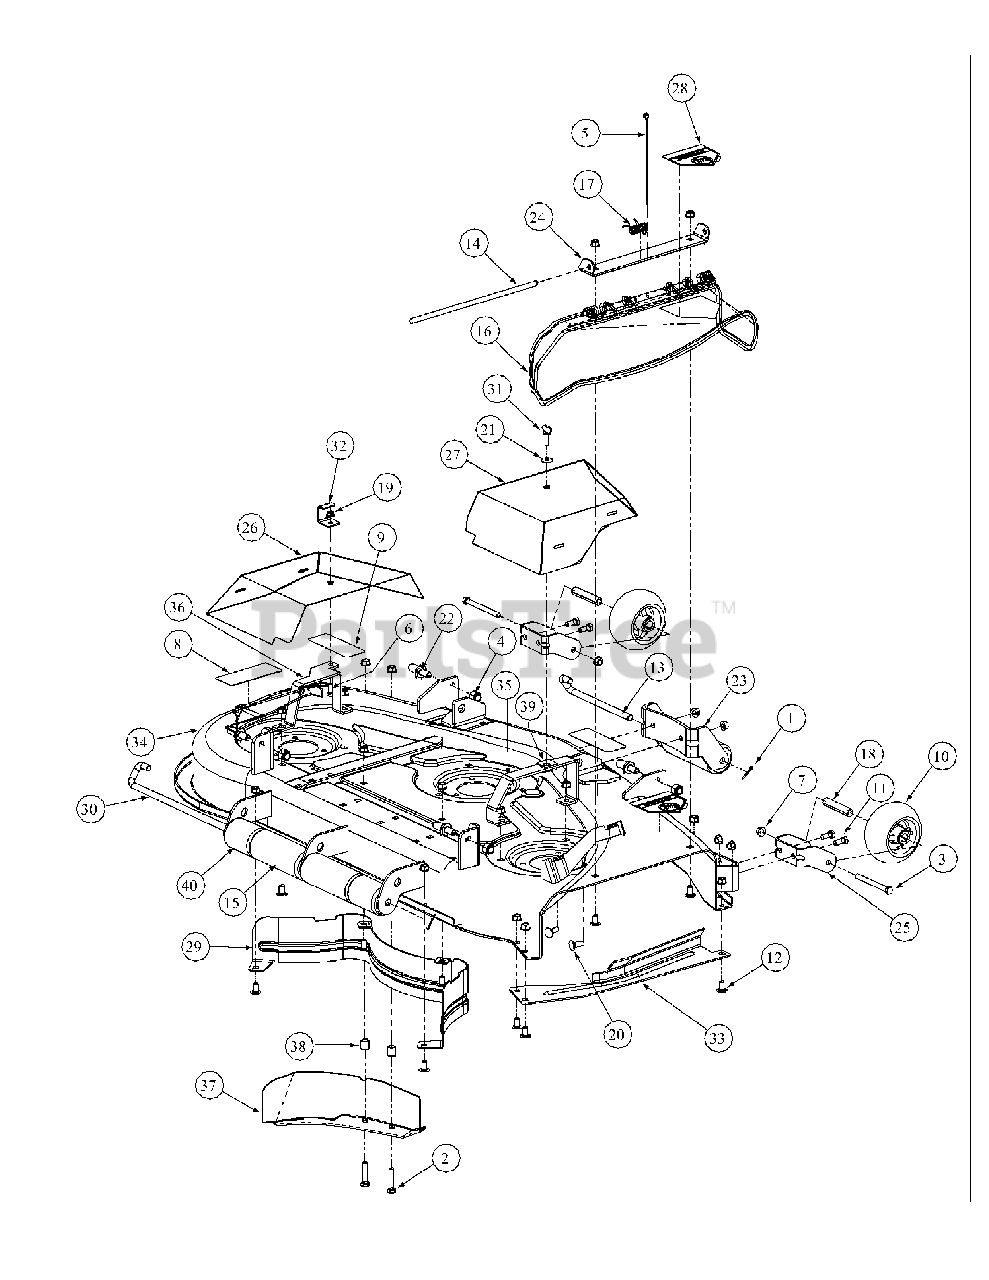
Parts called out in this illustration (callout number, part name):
1	Cotter Pin, .125 Dia x 1.0
2	Capscrew, 3/8-16 x 1-3/4
3	Hex Cap Screw, 3/8-16, 3.75
4	Lock Nut, Nylon Insert, 1/2-13
5	Cable Tie, 3/16 x .05 x 7.4
6	Hex Cap Screw, 5/16 -18 x 3/4
7	Hex Nut Flange Lock, 3/8-16
8	Decal, Rotating Blade
9	Decal, Warning Shield Missing
10	Wheel, 5.00 Dia
11	Hex Cap Screw, 3/8-16 x .75 Lg
12	Carriage Bolt, 3/8-16 x .75 Lg
13	Roller Pin, 1/2 Dia x 7.31 Lg
14	Hinge Pin, .375 x 12.93
15	Front Roller
16	Deflector Chute
17	Torsion Spring
18	Spacer Wheel
19	Hex Flange Lock Nut, 5/16-18
20	Carriage Bolt, 3/8-16 x 1
21	Belle Washer, .325 x .930 x .045
22	Pin, 5/8 Dia x 1.2 Lg
23	Front Roller Bracket
24	Chute Mounting Bracket
25	Castor Bracket
26	48" Left Hand Belt Cover
27	48" Right Hand Belt Cover
28	Decal, Danger Hands and Feet
29	48" Right Rear Inner Baffle
30	Roller Pin Rod
31	Thumb Screw, 5/16-18 x 1.0 Lg
32	Tension Rod Stop Bracket
33	Finger Guard
34	48" Stamped Deck
35	48" Right Hand Belt Cover Support Bracket
36	48" Left Hand Belt Cover Support Bracket
37	48" Deck Baffle
38	Spacer, .385 ID x .75 OD x .875
39	U-Nut, 5/16-18
40	Short Roller
